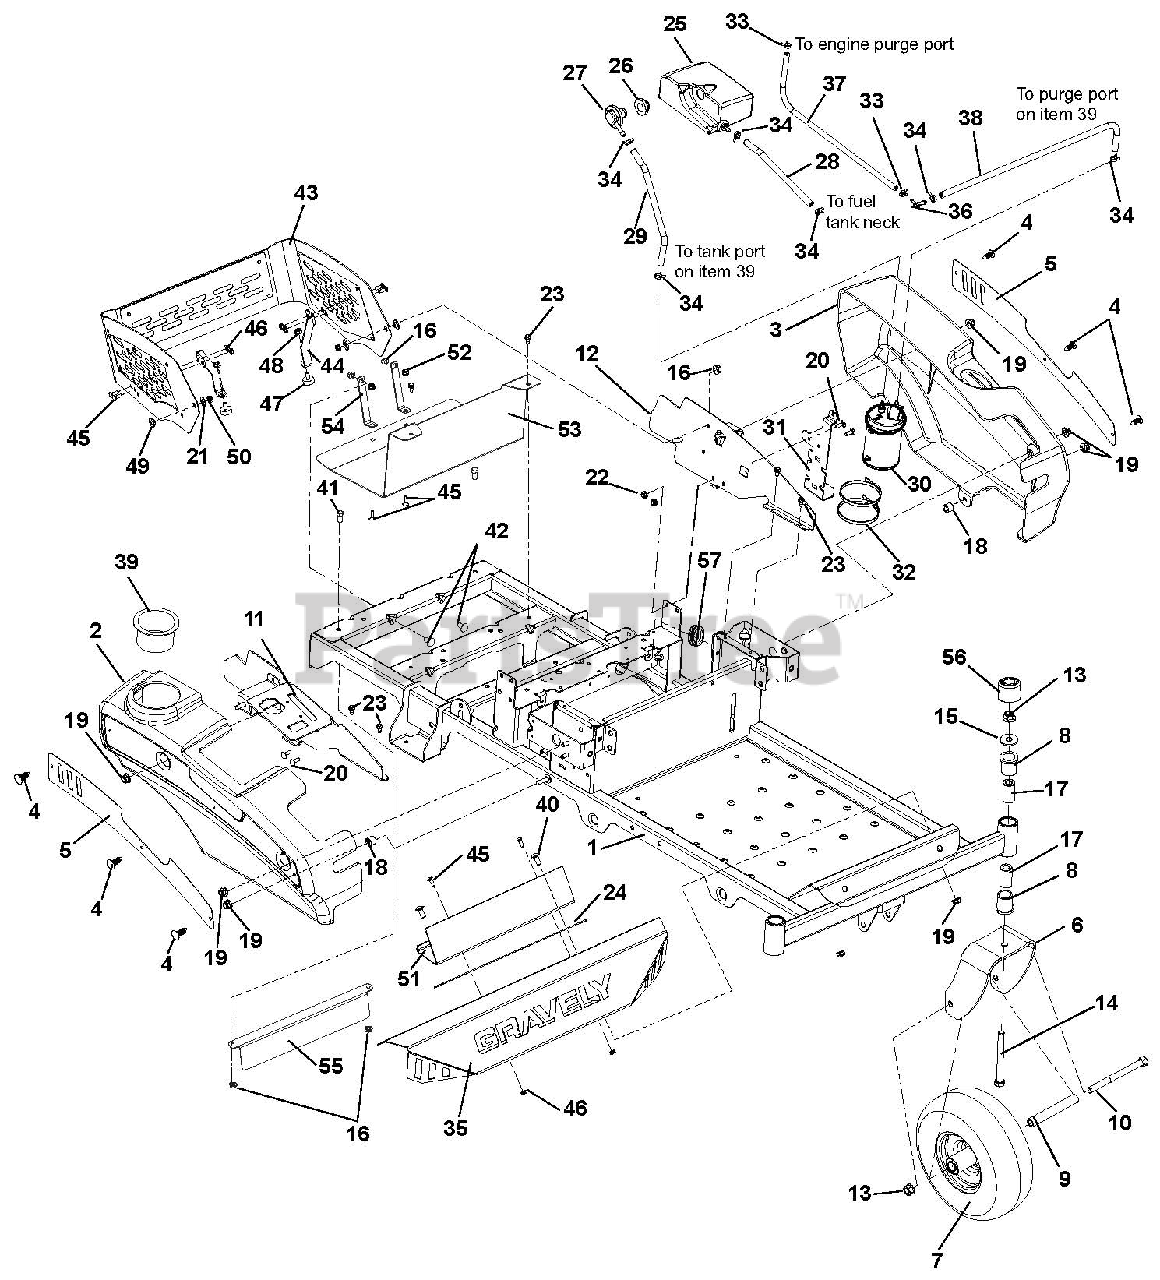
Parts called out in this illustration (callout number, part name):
1	Weldment, Frame
2	Fender, Right Hand
3	Fender, Left Hand
4	Rivet, Nylon
5	Plate, Fender
6	Fork, Caster
7	Wheel/Tire Assembly, 11 x 4-5
8	Bushing, Flange 1.00 x 1.25 x 1.50 x 1.50
9	Spacer, Wheel
10	Bolt, Hex .50-13 x 6.50
11	Weldment, Fender Mount Right Hand
12	Weldment, Fender Mount Left Hand
13	Nut, Locking Top Flange .50-13
14	Bolt, Hex .50-13 x 5.00
15	Washer, Flat Steel .511 x 1.441 x .125
16	Nut, Locking Top Flange .38-16
17	Spacer, Caster
18	Bushing, Sleeve .391 x .688 x .52
19	Nut, .31-18 Nyloc Flange
20	Bolt, Round Head Square Neck .25-20 x .75
21	Washer, Flat Nylon .52 x 1.00 x .08
22	Nut, .25-20 Nyloc Flange
23	Screw, Tapping .25-20 x .50 Hex Washer Head Thread
24	Grip, Adhesive
25	Expansion Tank Subassembly
26	Grommet, Remote Vent Nitrile
27	Vent, Roll-Over, .25" ID Hose
28	Hose, .25 Low-Perm Bulk Gas
29	Hose, .25 Low-Perm Bulk Gas
30	Carbon Canister, 300CC
31	Bracket, Mount, Canister BBZ
32	Plastic Tie Strap Large
33	Clamp, Hose Spring .188
34	Clamp, Hose Wire .490/.510 x .116
35	Foot Rest
36	Fitting, 3/16 x 1/4 90 Deg Vac
37	Hose, .188 Low Perm Bulk
38	Hose, .25 Low Perm Bulk Gas
39	Cupholder
40	Bolt, Round Head Square Neck .31-18 x .75
41	Bolt, Hex .38-16 x 1.00
42	Bolt, Round Head Square Neck .38-16 x 1.00
43	Assembly, Engine Wrap
44	Bracket, Engine Wrap Foot
45	Bolt, Round Head Square Neck .25-20 x .50
46	Nut, Center Lock Flange .25-20
47	Bumper, Rubber
48	Nut, Serrated Flange .31-18
49	Bushing, Flange .325 x .499 x .3 x .875
50	Nut, Center Lock Flange .31-18
51	Plate, Back Foot Rest
52	Nut, Locking Top Flange .25-20
53	Guard, Heat Shield, ZT
54	Strap, Heat Shield, ZT
55	Guard, Hot Surface, ZT
56	Cap, Dust
57	Grommet, 1.0 I.D. x 1.38 O.D.
